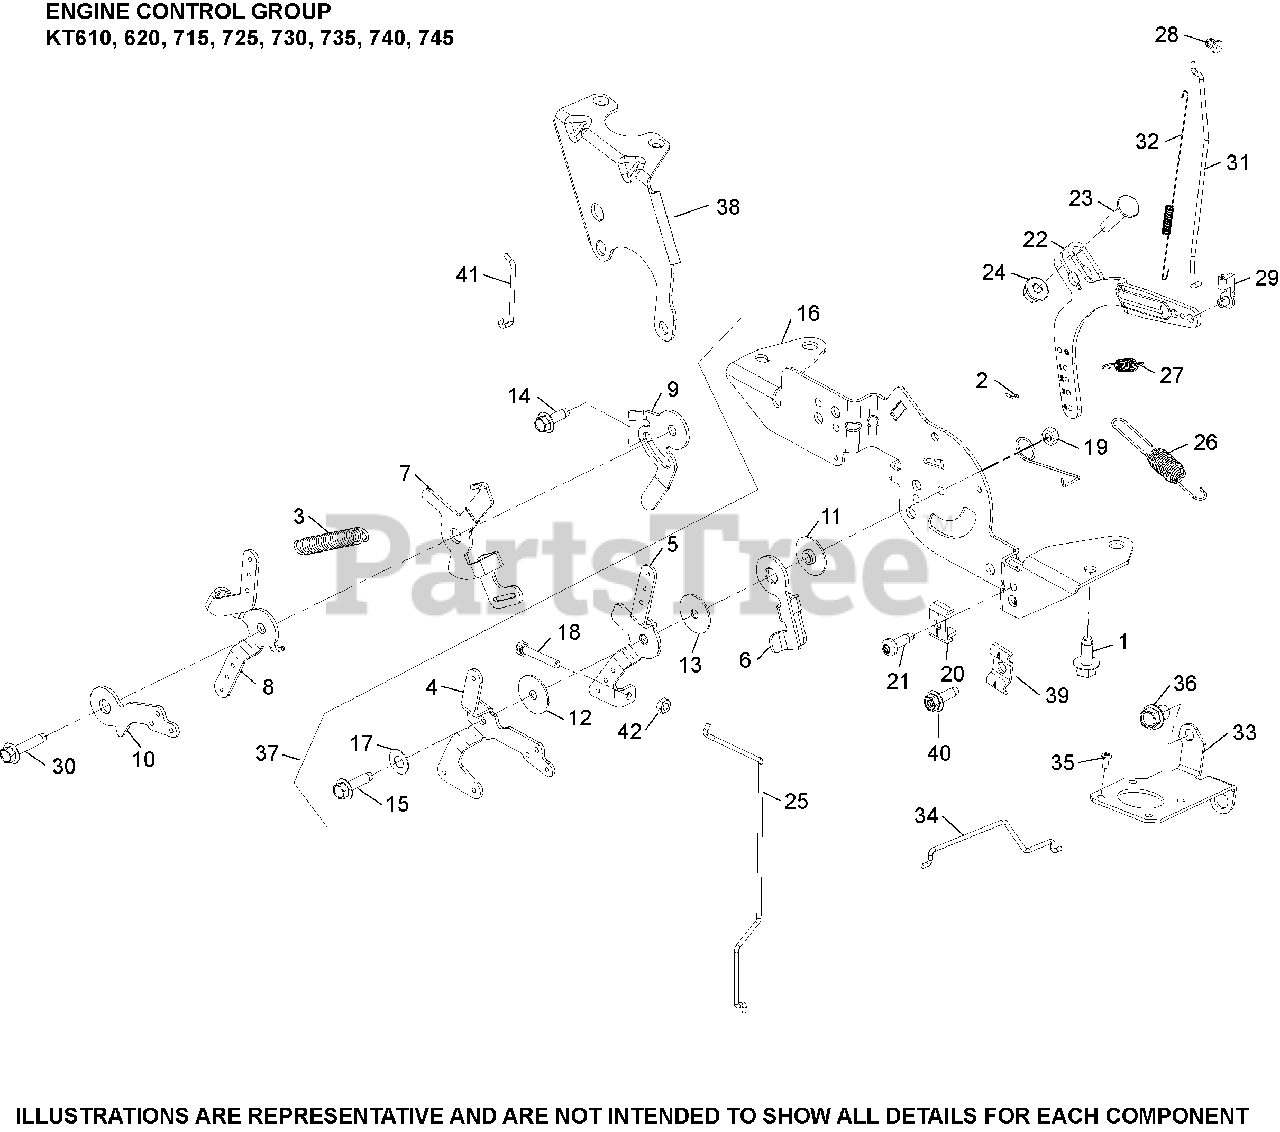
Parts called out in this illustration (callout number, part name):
1	SCREW, THREAD FORMING
2	SPRING, CHOKE RETURN
4	LEVER, CHOKE
5	LEVER, THROTTLE CONTROL
6	LEVER, THROTTLE ACTUATOR
11	SPACER, CONTROL ASSEMBLY
12	WASHER, FLAT 5.5 MM
13	WASHER, FLAT 5 MM
14	SCREW, THREAD FORMING
15	SCREW, THREAD FORMING - USE 25 086 473-S
16	BRACKET, CONTROL USE 32 126 18-s
17	WASHER, SPRING 1/4"
18	SCREW, SLT HD CAP M4X0.7X25
19	NUT, LOCK M5X.8
20	CLAMP, CABLE
22	LEVER, GOVERNOR - (#2409069S)
23	BOLT, RD HD SQ NECK M6X1.0X25
24	NUT, FLG M6X1.0
25	LINKAGE, CHOKE
26	SPRING, GOVERNOR (PURPLE)
27	SPRING, GOVERNED IDLE
28	BUSHING, LINKAGE RETAINING
29	BUSHING, THROTTLE LINKAGE
32	SPRING, LINKAGE USE 32 089 11-S
34	LINKAGE, THROTTLE
40	SCREW, THREAD FORMING
42	NUT, M4X0.7
